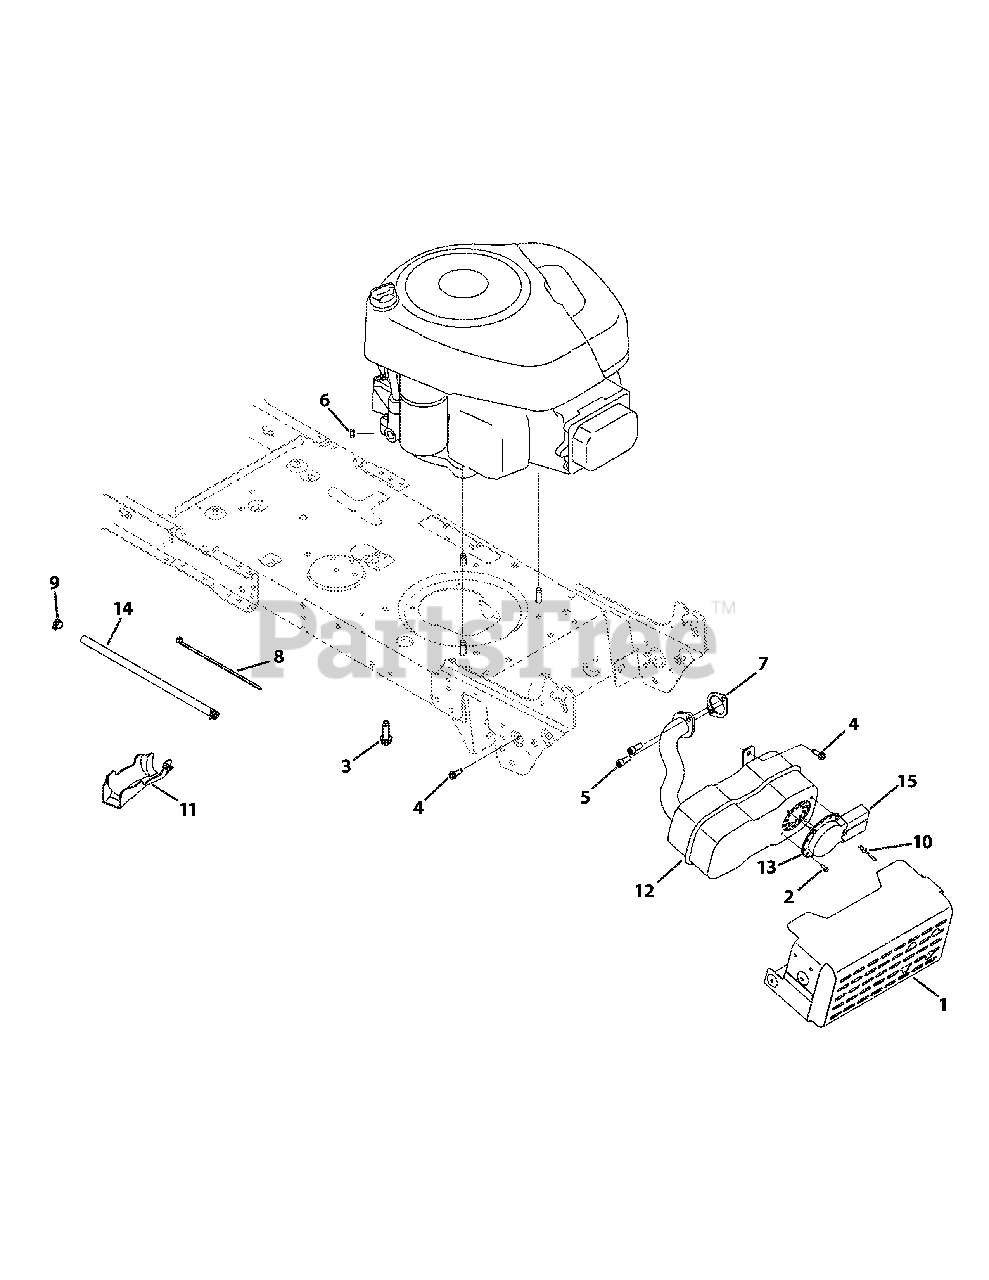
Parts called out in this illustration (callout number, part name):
1	Muffler Shield Assembly with Weld
2	Screw, 8-18 x .500
3	Screw, 3/8-16 x 1.0
4	Screw, 1/4-20 x .750
5	Socket Screw, 5/16-18 x .750
6	Sems Nut, 1/4-20
7	Exhaust Gasket, 10 HP Briggs
8	Cable Tie
9	Clamp Hose, .490 diameter
10	Rivet, .188 x .300
11	Oil Drain Sleeve
12	Muffler, Single Inlet
13	Muffler Deflector
14	Fuel Hose, Low Permeation
15	Muffler Deflector Long
